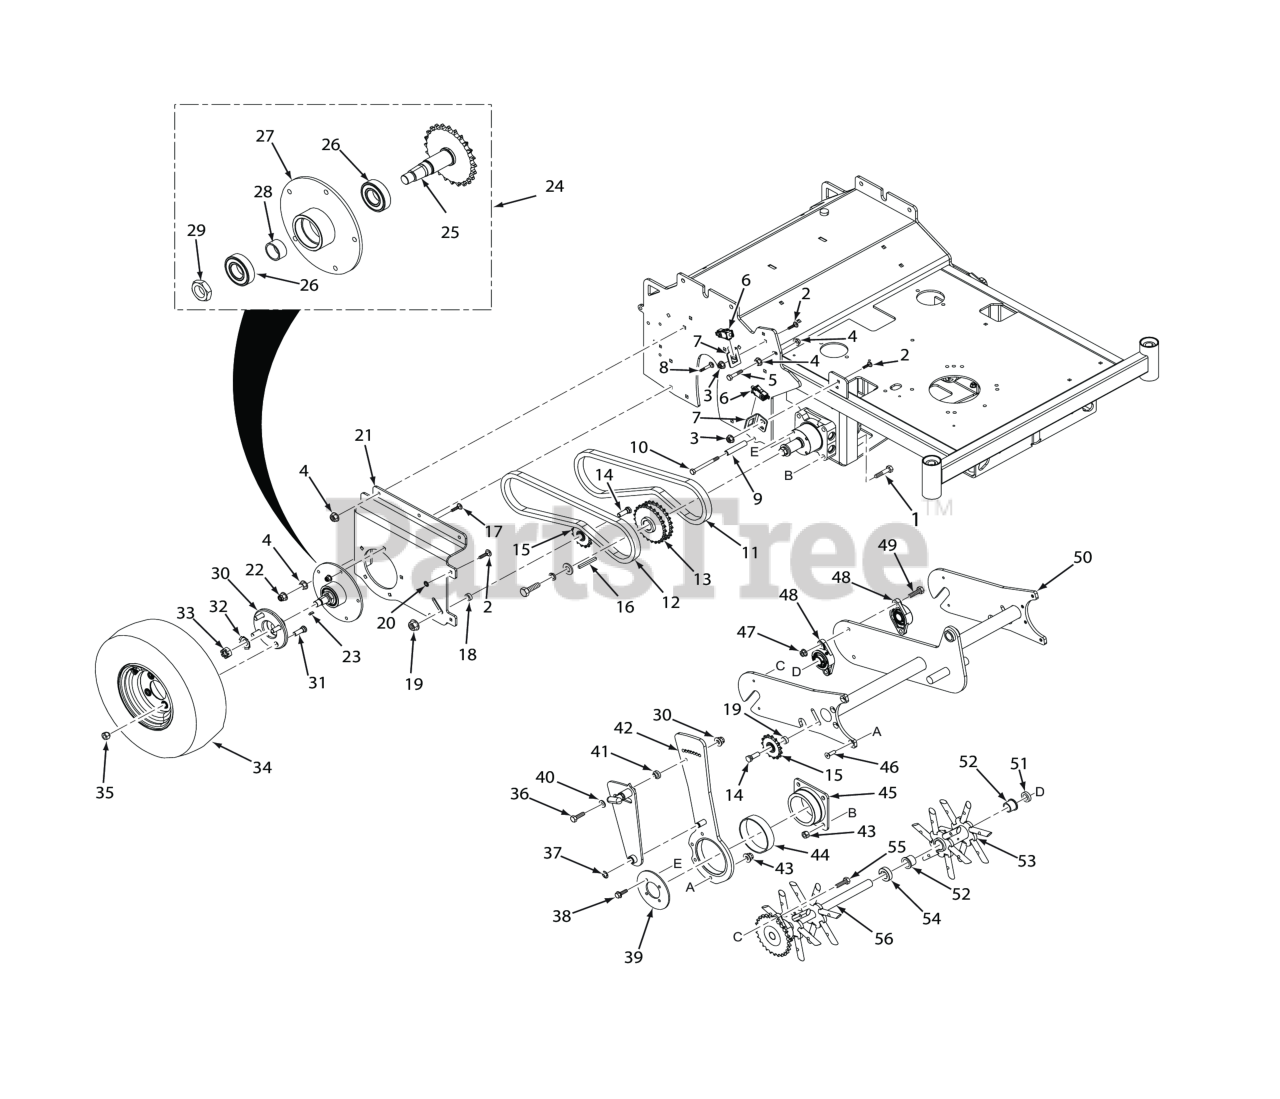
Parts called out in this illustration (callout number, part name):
1	Bolt, Hex Head 1/2-13 x 2-3/4" (48V & 52V - One Weight)
2	Bolt, 5/16-18 x .75 RHSN Carriage
3	Nut, Serrated Flange 5/16-18 (Right Front Engine Mounting, Briggs and Kohler Only)
4	NUT, 3/8-16 SERRATED FLANGE HEX HEAD
5	Capscrew, Hex Head 3/8-16 x 2.0"
6	Switch, Plunger, Double Pole, Snap
7	Bracket, Height Switch
8	Carriage Bolt, 3/8-16 x 2-1/2"
9	Spacer, Wheel Mount
10	Bolt, Hex Head 3/8-16 x 4.00
11	Chain, Tine Drive
12	Chain, Wheel Drive
13	Sprocket, Motor
14	Bolt, Ilder Sprocket
15	Sprocket, Idler 15T
16	Key, 5/16 x 5/16 x 1.437
17	Carriage Bolt, 3/8-16 x 1.0"
18	Bushing, Idler Sprocket
19	Nut, Hex Serrated Flange 1/2-13
20	Nut, Push-On 5/16-18
21	Bracket RH, Wheel Mount
22	Nut, Flange Elastic Stop Nut, 3/8-16
23	KEY, WOODRUFF #9, 3/16 X 3/4"
24	Assembly (incl. #18, 19, 20, 21, 22)
25	Shaft, Wheel
26	Bearing, Ball 30mm Bore x 62mm OD
27	Hub, Wheel
28	Spacer, Wheel Bearing
29	Nut , Spec ial 1 -1/ 1 6 - 1 8
30	Wheel Hub Assembly
31	Bolt, Serr. Flange 1/2-20 x 4.563"
32	Lock Washer, Wheel Motor
33	Hex Castle Nut, 3/4-28 UNEF
34	Wheel Assy., 18 x 6.5 - 8
35	Wheel Nut, 1/2-20 x 13/16
36	Bolt, Hex Head 3/8-16 x 1-1/2" B&S 32BV
37	RETAINING RING, 5/8" EXTERNAL "E"
38	Capscrew, 5/16-18 x .75 Serrated Flange Hex Head
39	Stop Plate, Pivot Bearing
40	Flatwasher, 3/8 (.391 x .938 x .105 HD) Grade 8
41	BUSHING, SPEED ADJUSTMENT LEVER
42	Pivot Bearing Wlmt RH
43	HEX NUT, ELASTIC STOP LOCK, 3/8-16
44	Pivot Bearing
45	Pivot Bearing Wlmt
46	Capscrew, 3/8-16 x 1-1/4"
47	HEX NUT, 7/16-14 SERRATED FLANGE
48	Bearing, 1" Flange
49	BOLT, HEX HEAD, 7/16-14 X 1-3/4
50	Pivot Arm Wlmt
51	Flatwasher, 1" (1.062 x 1.75 x .10)
52	Bushing, 1" ID Oilite
53	Tine Wlmt, Idler
54	Clamp Collar, 1.25 Bore 2 Piece
55	Bolt, Hex Head 7/16-20 x 1"
56	Tine Wlmt, RH Drive
